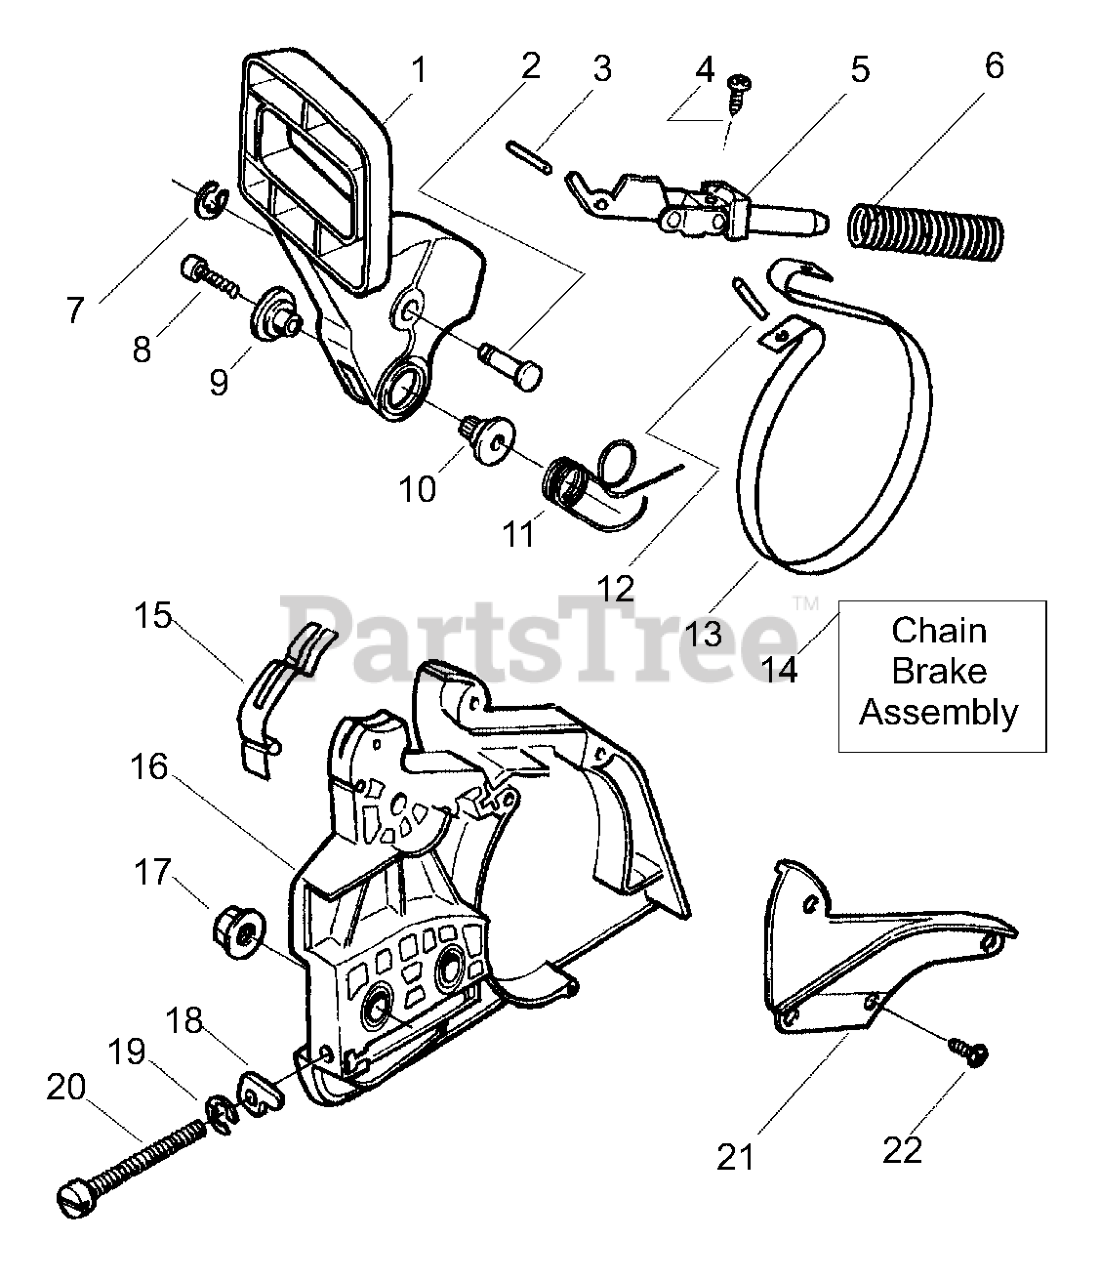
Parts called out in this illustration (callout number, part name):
5	FRONT LINK ASSY
9	PIVOT SLEEVE R
10	PIVOT SLEEVE L
11	SPRING,BRK HDL 36/41
12	SPIRAL PIN 4X12
13	BRAKE BAND
14	CHAIN BRAKE ASM.
15	SPRING-POSITION
16	CLUTCH COVER
18	ADJUST PIN,BAR 36/41
20	BAR ADJUSTING SCREW
21	CHAIN BRAKE COVER
